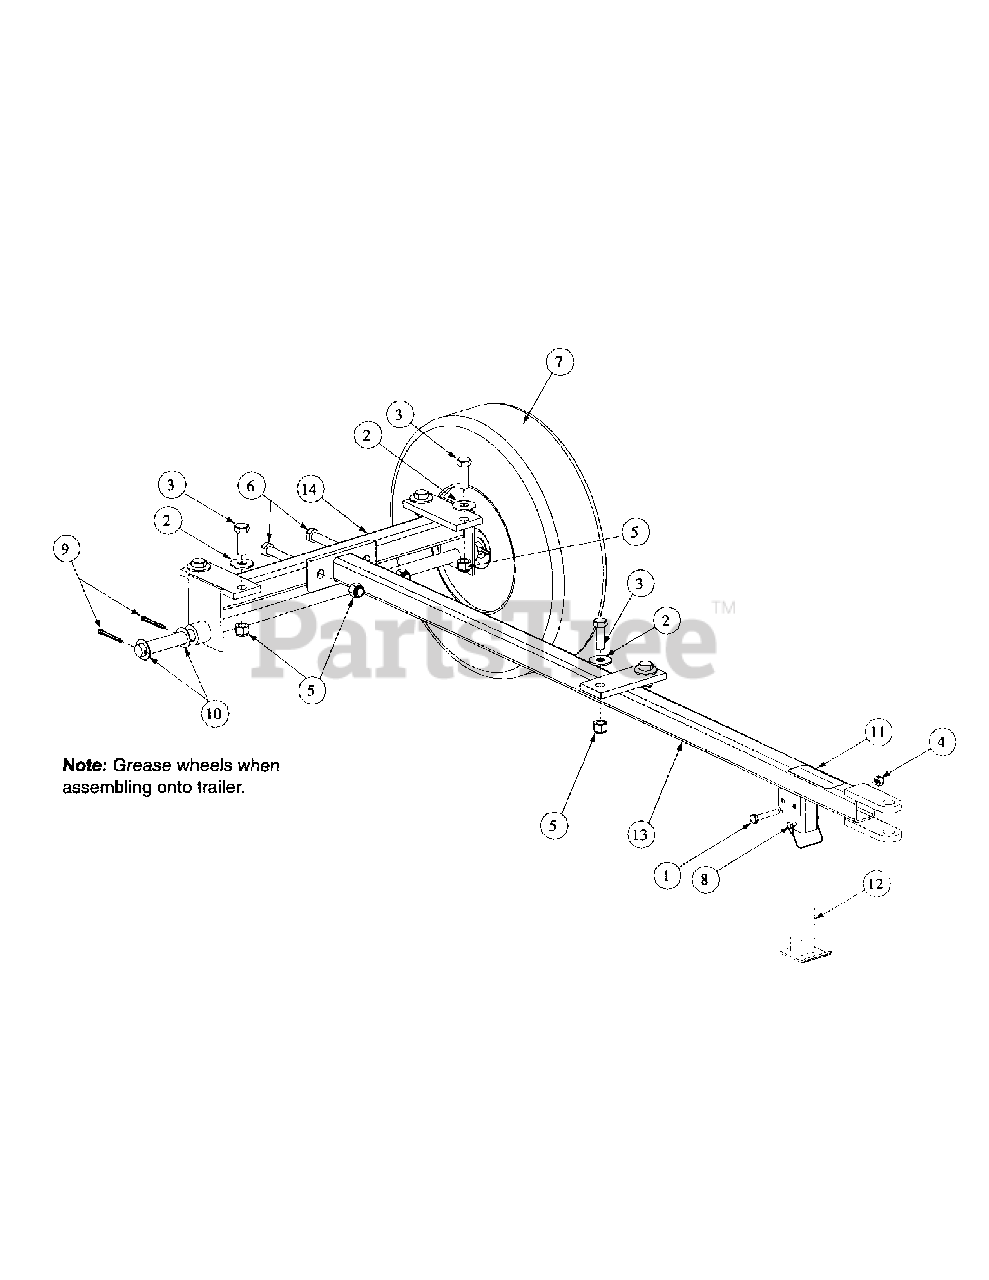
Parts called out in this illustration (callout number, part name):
1	Hex, Cap, Screw, 5/16-18, 1-3/4
2	Flat, Washer, 1/2, USS, Zinc
3	Hex, Cap, Screw, 1/2-13, 1-1/2
4	Nut, Nylock, 5/16-18
5	Lock Nut, Nylon Insert, 1/2-13
6	Hex, Cap, Screw, 1/2-13, 2-1/2
7	Tire and Wheel Assy, 4.80/4.00-8
8	Lynch Pin, 1/4, 2, Zinc
9	Cotter Pin, SS, 3/16, 1-3/4
10	Flat, Washer, SS, .06, .776, 1.25
11	Decal, "Not For Highway Use"
12	50 Gallon, Trailer Stand, Frame
13	50 Gallon, Hitch Assy, Frame
14	50 Gallon, Axle Assy, Frame
